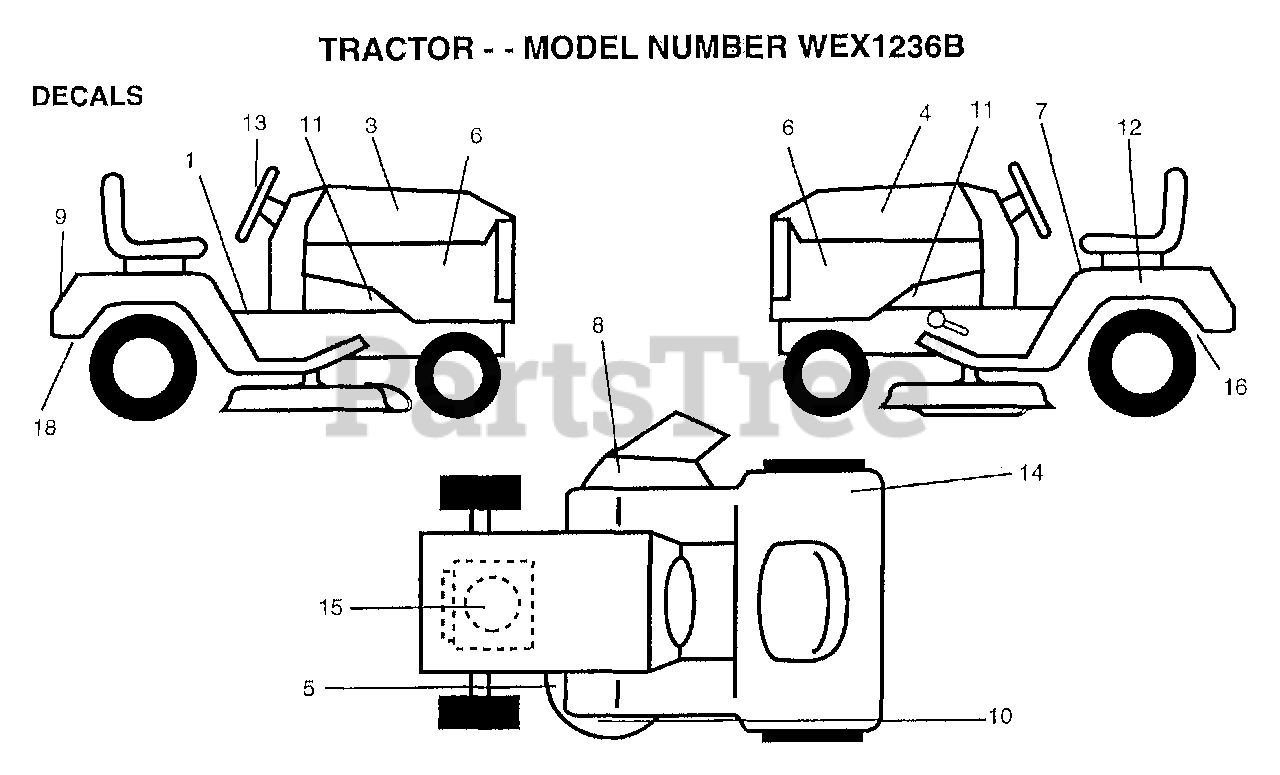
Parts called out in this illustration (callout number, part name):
1	DECAL CLUTCH/BRAK
3	DECAL.HOOD.RH
4	DECAL.HOOD.LH
5	DECAL.V.BELT
6	DECAL.PNL.SIDE
7	DECAL.READ.O.MANU
8	DECAL.DANGER.CUTF
9	DECAL.FENDER.LOGO
10	DECAL, DECK GRASSEATER
11	"DECAL CHASSIS,HOT"
12	DECAL.BATRY.3-3908
13	DECAL INSRT STEER
16	DECAL.DRAWBAR.LDL
18	DECAL.EURO.ST.CE.
